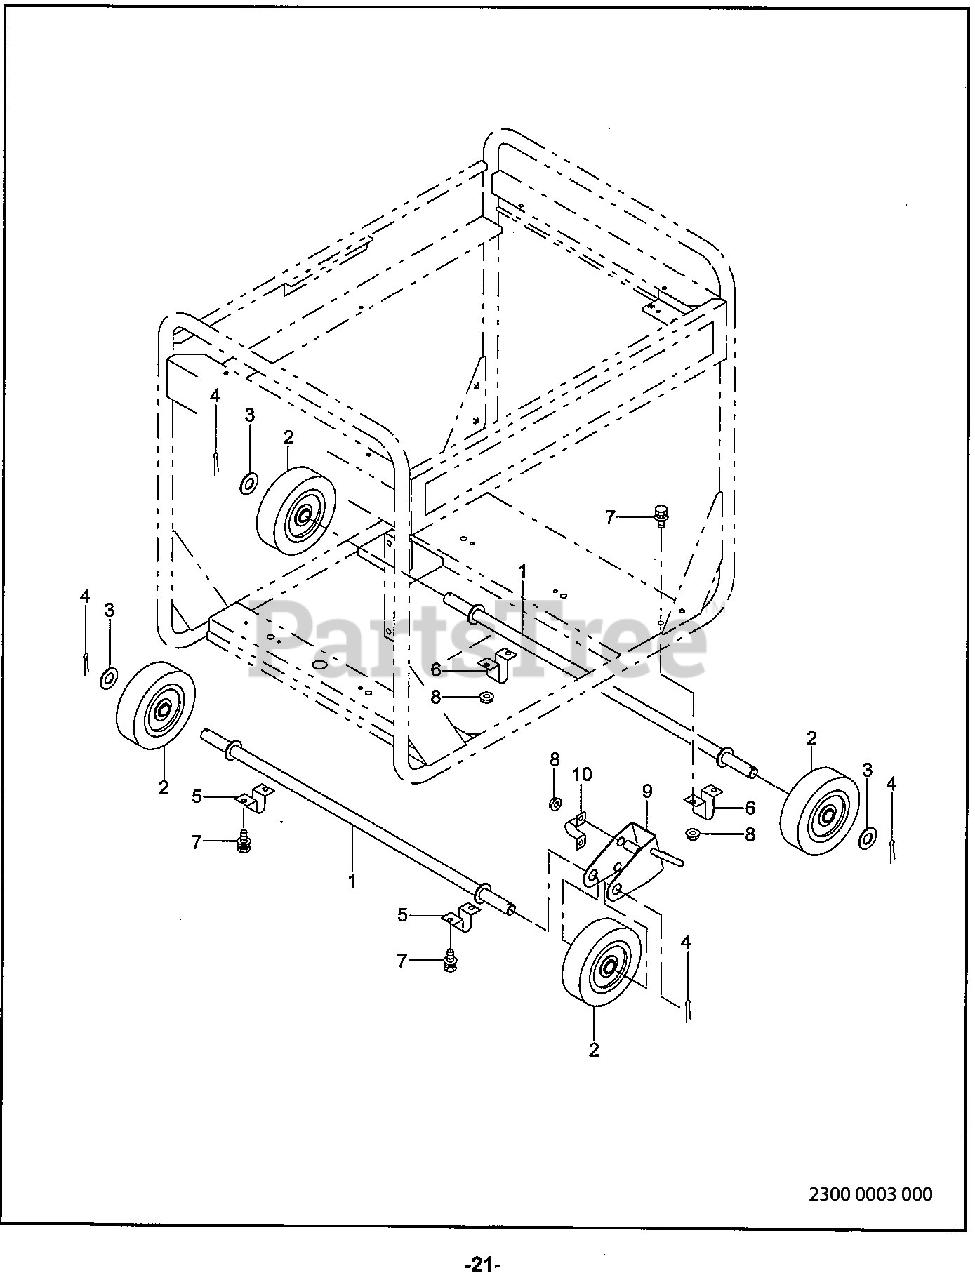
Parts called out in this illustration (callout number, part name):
5	BRACKET (generator side)
6	BRACKET (engine side)
7	BOLT and WASHER ASSY
